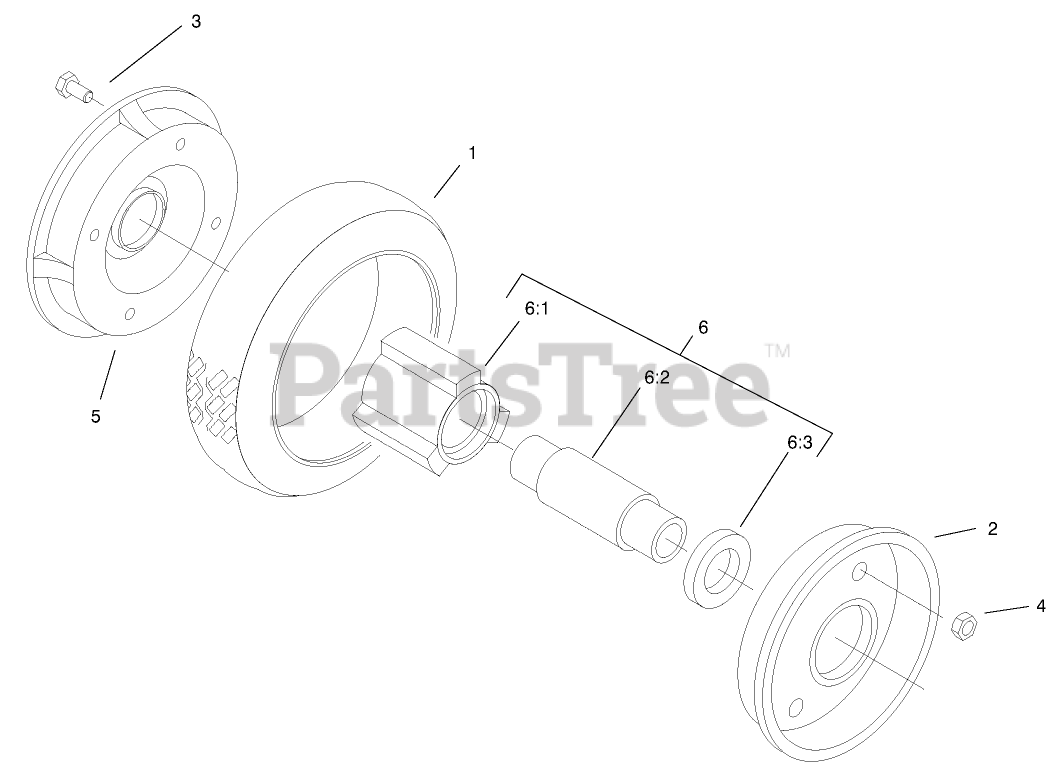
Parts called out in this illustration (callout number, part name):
3	SCREW-HH
4	NUT-LOCK, NI
6	Hub and Bearing ASM
6:1	HUB-BEARING
6:2	SPACER-BEARING
6:3	BEARING-WHEEL
